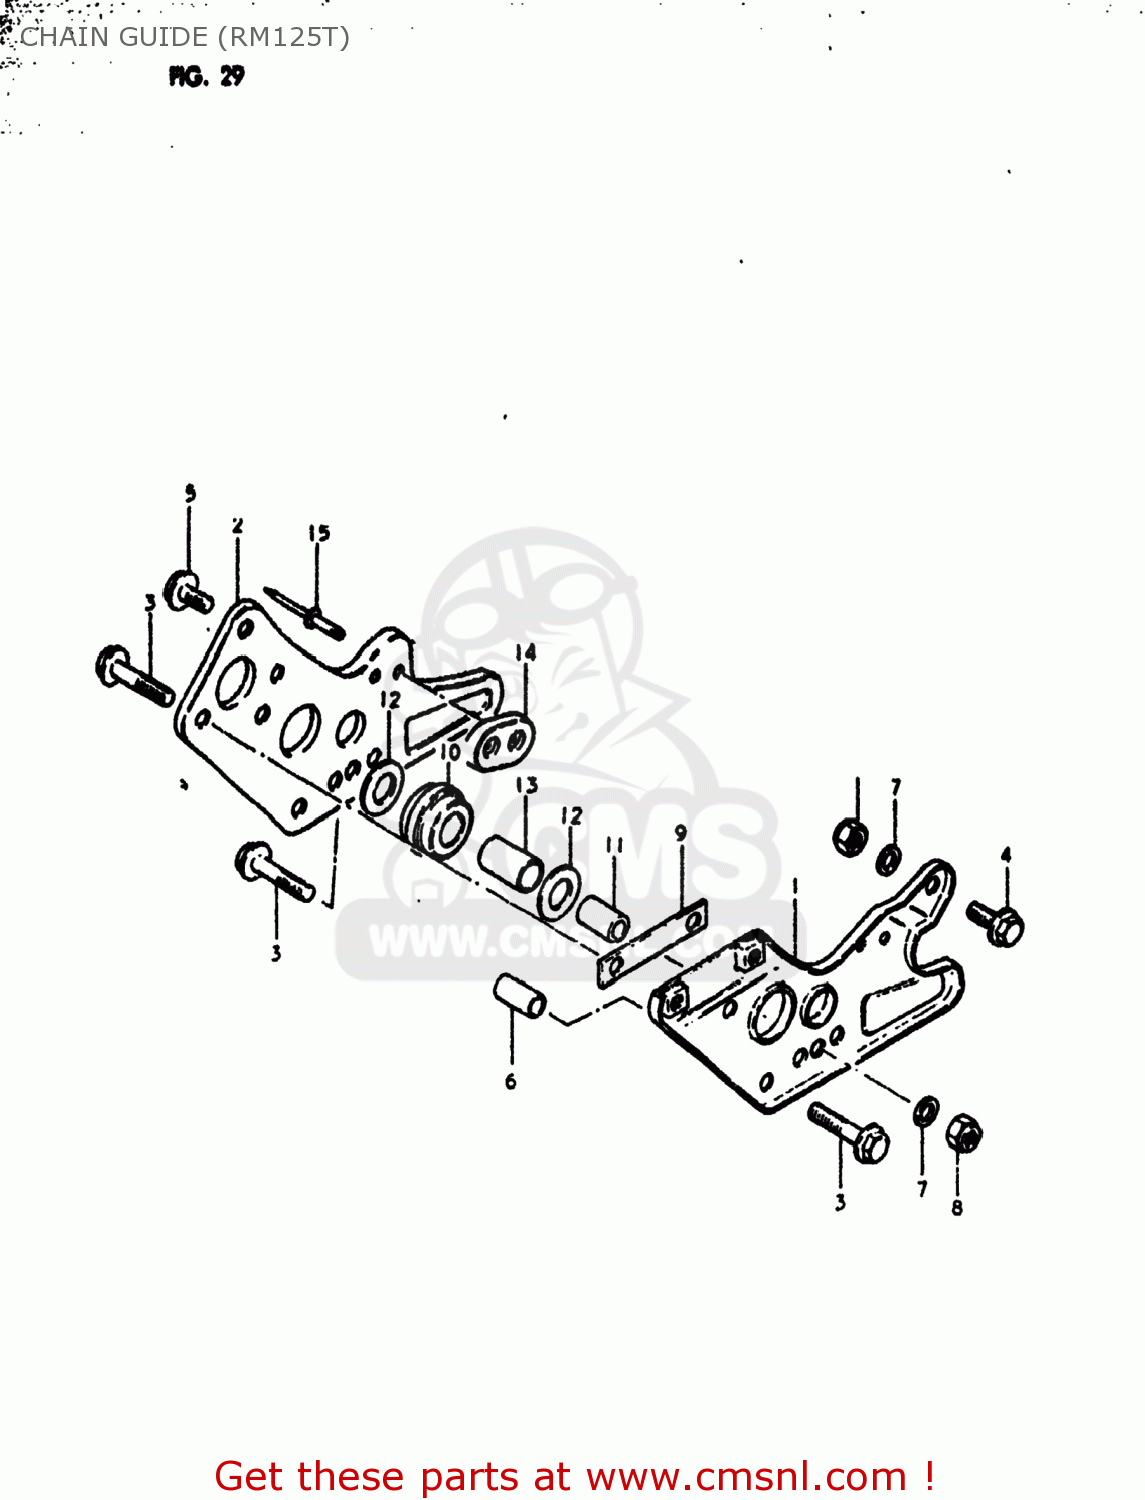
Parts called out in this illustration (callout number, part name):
1	PLATE,CHAIN GUIDE,OUTER
2	PLATE,CHAIN GUIDE,INNER
3	BOLT 6X35
4	BOLT
5	BOLT
6	SPACER(6.8X10X24.2)
7	WASHER
8	NUT 6MM
9	WASHER
10	ROLLER,CHAIN GUIDE
11	SPACER,CHAIN GUIDE ROLLER
12	WASHER
13	BUSHING
14	PAD
15	RIVET
